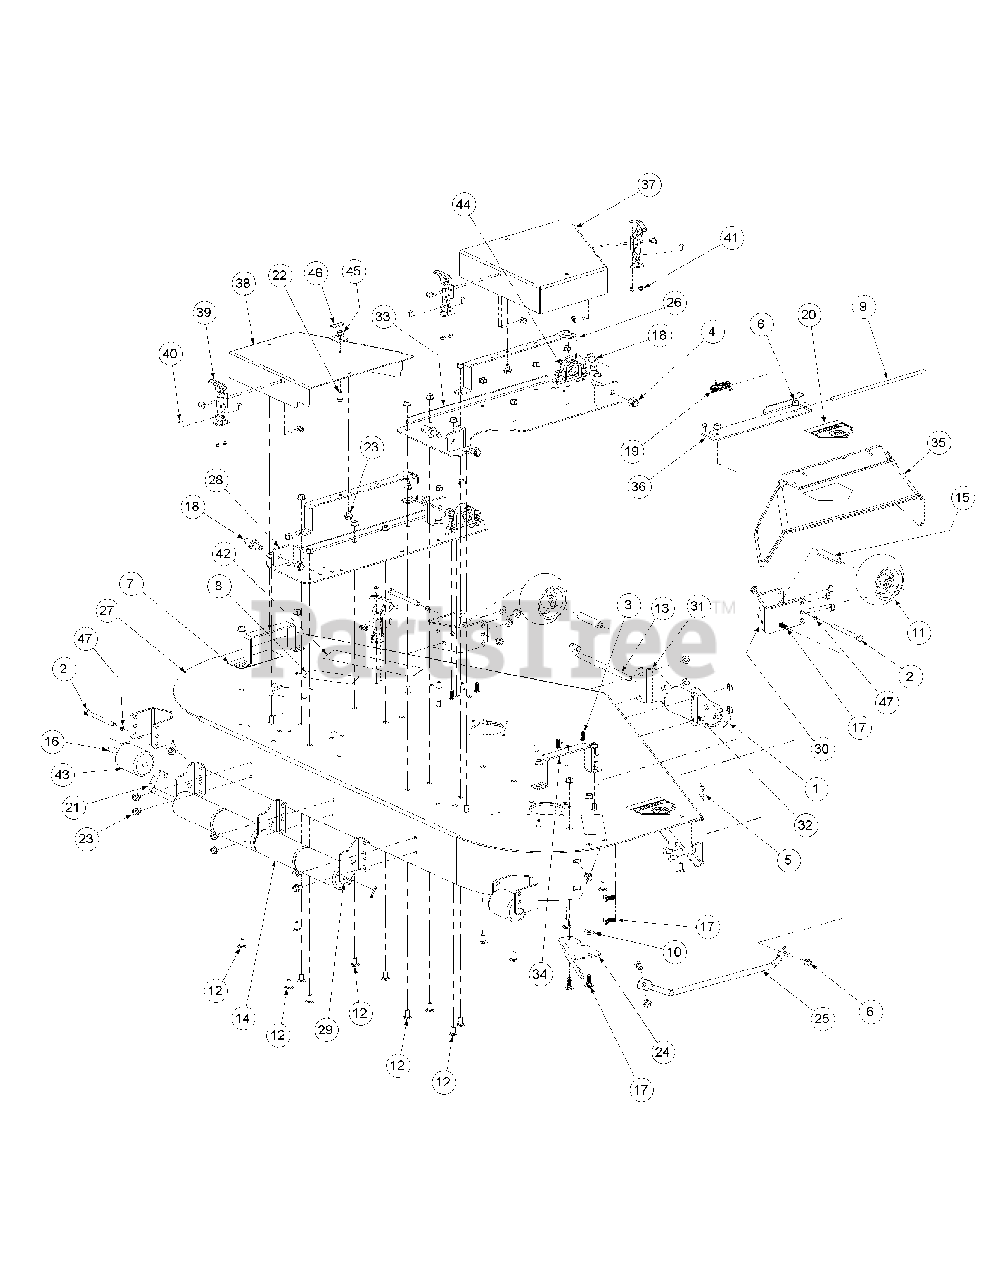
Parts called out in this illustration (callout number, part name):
1	Cotter Pin, .125 Dia. x 1.0
2	Hex Cap Screw, 3/8-16, 3.75
3	Carriage Screw, 3/8-16 x 1.25
4	Lock Nut, Nylon Insert, 1/2-13
5	Label, 60"
6	Flange Lock Hex Nut, 3/8-16
7	Decal, Rotating Blade
8	Decal, Warning Shield Missing
9	Chute Deflector Rod
10	Idler Washer
11	Complete Wheel, 5.00 Dia.
12	Carriage Bolt, 3/8-16 x .75 Lg.
13	Roller Pin, 1/2 Dia. x 7.31 Lg.
14	Front Roller
15	Wheel Spacer
16	Spacer, .385 x .50 x 3.045
17	Carriage Bolt, 3/8-16 x 1
18	Pin, 5/8 Dia. x 1.2 Lg.
19	Torsion Spring, 0.4ID x 2.16Lg
20	Decal, Danger Hand and Feet
21	Roller Pin
22	Hex Cap Screw, 5/16-18 x .75
23	Hex Index Washer Screw, 3/8-16, .5
24	Chute Bracket
25	Finger Guard
26	Belt Cover Support
27	60 Deck Assembly
28	Left Hand Mount Deck Bracket Assembly
29	Deck Roller Mount Bracket
30	Anti-Scalp Wheel Front Mount Bracket
33	Right Hand Deck Bracket Assembly
34	Outer Belt Cover Support Assembly
35	Chute Deflector
36	Chute Deflector Bracket
37	Right Hand Deck Belt Cover
38	Left Hand Deck Belt Cover
39	T-Handle Latch Draw
40	Phillips Head Screw, 10-32
41	Lock Nut, Nylon Insert, 10-32
42	Commercial Mower Label
43	Grass Catcher Roller
44	Pillow Block
45	Nut, 5/16-18, Hex Flange Lock
46	Stop Bracket
47	Flat Washer, 3/8
